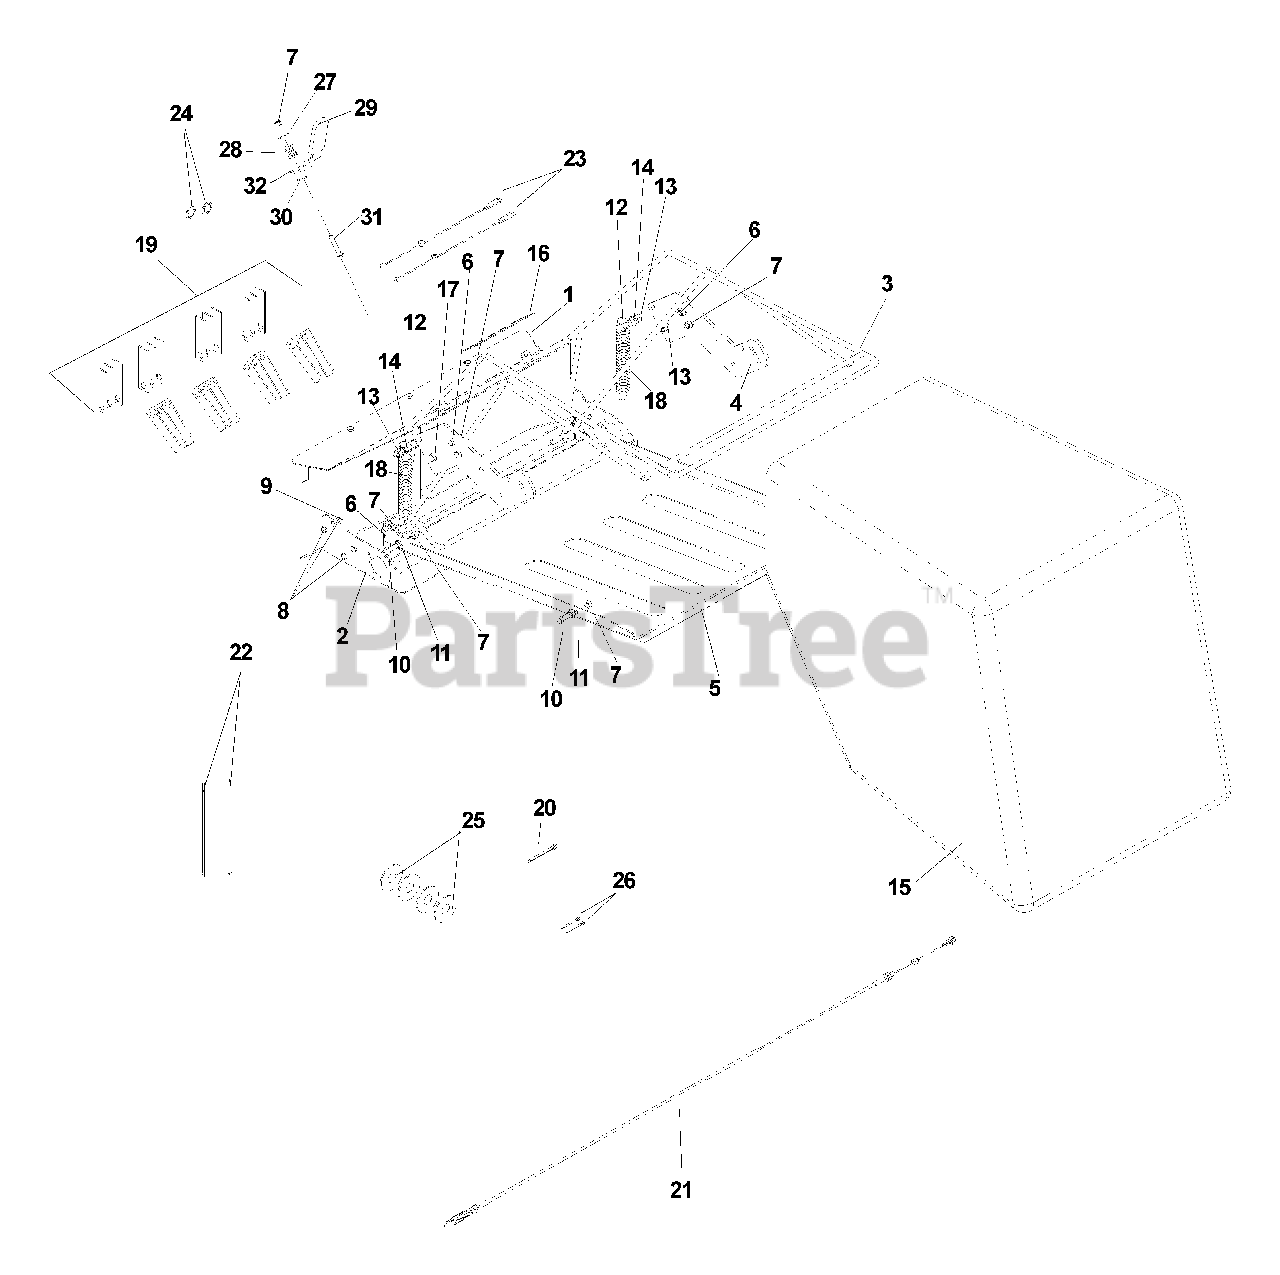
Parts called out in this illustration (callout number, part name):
1	CHUTE
3	BAG FRAME, BLACK
5	SAFETY DOOR
6	SCREW, 5/16 X 1
7	NUT, 5/16, NYLOC
8	SCREW, 1/4 X 3/4
9	NUT, 1/4, NYLOC
10	SCREW, 5/16 X 1 3/4
11	NUT, 5/16, SERRATED WASHER
12	SCREW, 3/8 X 2
13	NUT, 3/8, NYLOC
14	NUT, 3/8, SERRATED WASHER
16	DECAL, WARNING
17	SCREW, 3/8 X 1
18	SPRING, BAGGER
19	BLADE SET (56)
20	COTTER PIN 1/8 X 1 1/2 (FOR REAR AXLE)
21	CABLE, BAGGER
22	WIRE TIE
23	LANYARD
24	RETAINING RING
25	WASHER, 5/8, SAE (FOR REAR AXLE)
26	COTTER PIN, 3/32 X 3/4
27	WASHER, 5/16
30	WASHER, 3/8
31	RHSNB, 5/16-18 X 1 3/4
